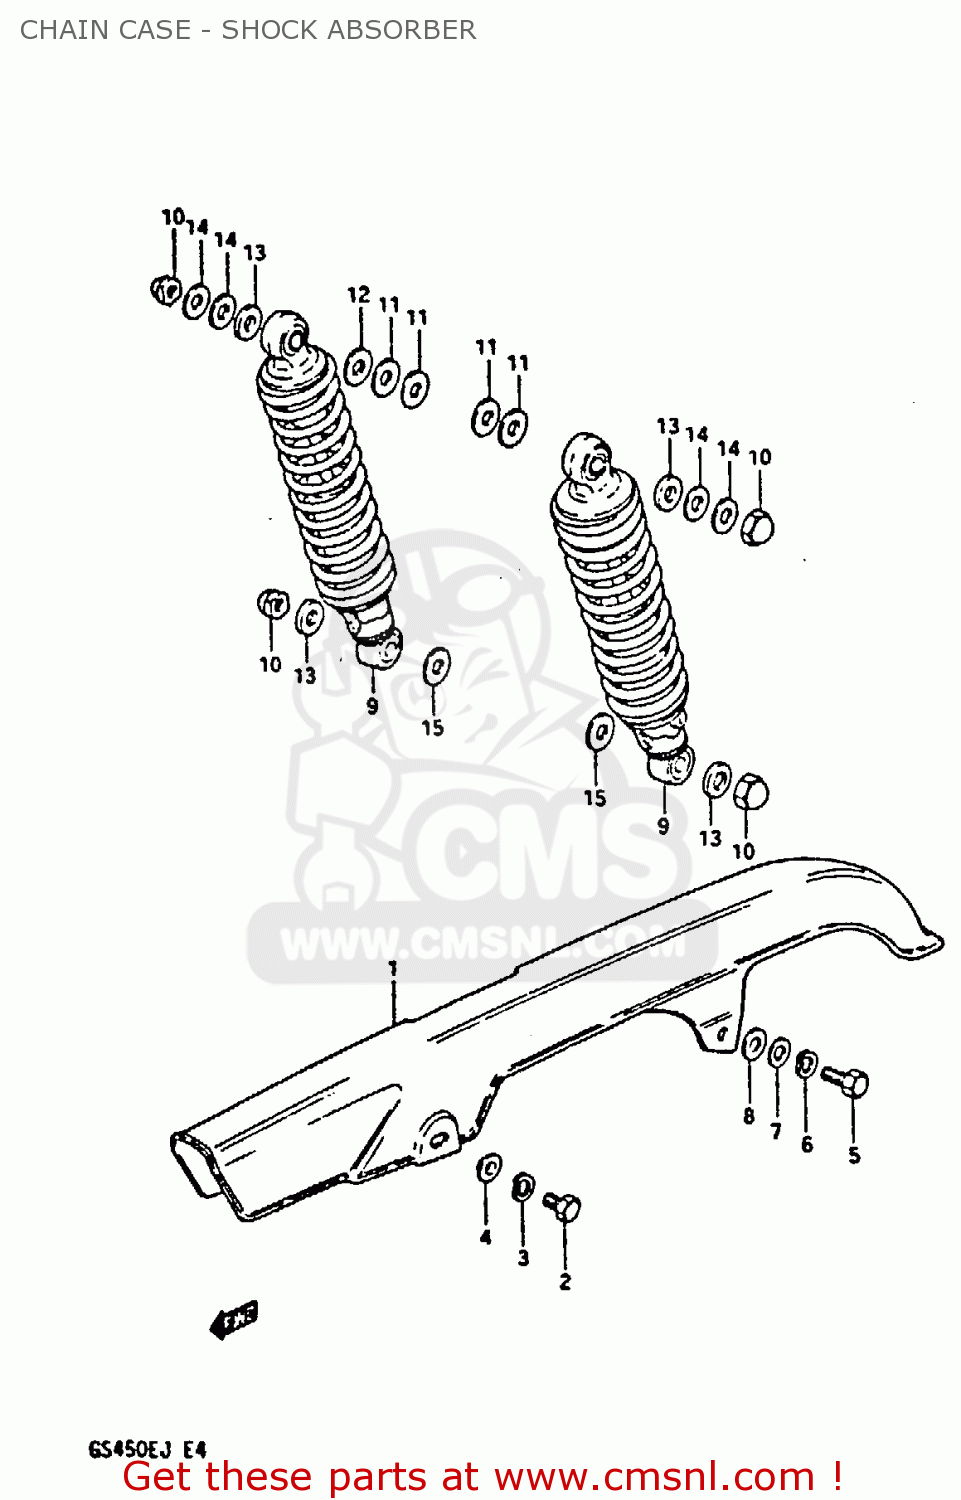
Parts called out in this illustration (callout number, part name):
1	CASE,CHAIN
2	BOLT
3	WASHER,LOCK
4	WASHER,LOCK
5	BOLT
6	WASHER,LOCK
7	WASHER
8	WASHER(6.5X18X1)
9	ABSORBER ASSY,RR SHOCK
10	NUT, LOWER LH
11	WASHER
12	WASHER (12.5X24X3.2)
13	WASHER
14	WASHER(10.5X24X3.2)
15	WASHER (12.5X24X1.6)
